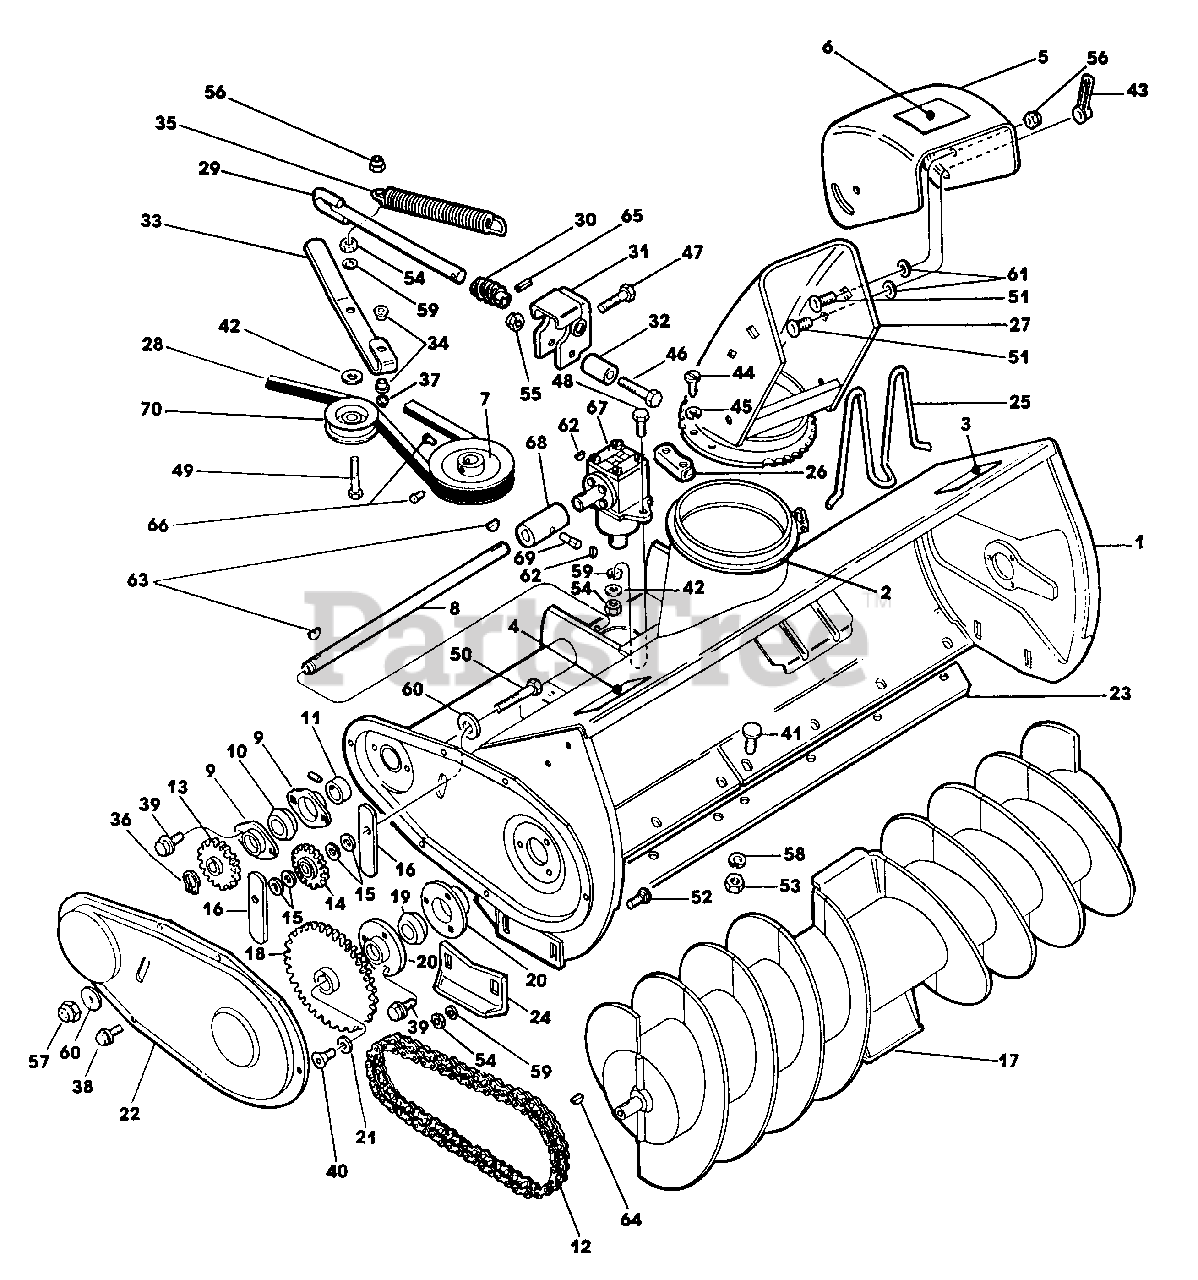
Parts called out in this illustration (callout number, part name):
1	Collector Housing Ass'y. w/Decals
2	Chute Collar
3	Decal-Warning
4	Decal-Danger
5	Chute Deflector & Decal Ass'y
6	Decal-Danger
7	Pulley, 4 1/2" Diameter
8	Output Shaft
9	Flangette Stamping
10	Bearing
11	Collar w/Setscrews
12	Chain
13	Sprocket
14	Idler Sprocket
15	Spacer
16	Strip
17	Auger
18	Sprocket
19	Bearing
20	Flangette Stamping
21	Washer
22	Drive Cover
23	Scraper Blade
24	Skid
25	Discharge Guard
26	Retainer
27	Discharge Chute
28	V-Belt (Secondary)
29	Worm Shaft
30	Worm Gear
31	Worm Support
32	Spacer-Worm Support
33	Idler Arm Assembly w/Bushings
34	Bushing
35	Spring-Idler
36	Snap Ring
37	Snap Ring
38	Lock Screw
39	Lock Screw
40	Flat Socket Hd. Screw
41	Wafer Hd. Bolt
42	Washer, Flat
43	Wing Nut
44	Screw, Self Tapping
45	Lock Washer, #6
46	Cap Screw, Hex Hd
47	Cap Screw, Hex Hd
48	Cap Screw, Hex Hd
49	Cap Screw, Hex Hd
50	Cap Screw, Hex Hd
51	Bolt, Carriage
52	Bolt, Carriage
53	Nut, Hex
54	Nut, Hex
55	Nut, Hex Cone Lock
56	Nut, Hex Cone Lock
57	Nut, Hex Cone Lock
58	Washer, Spring Lock
59	Washer, Spring Lock
60	Washer, Flat
61	Washer, Flat
62	Key, Woodruff
63	Key, Woodruff
64	Key, Woodruff
65	Roll Pin
66	Setscrew, Square Hd. Cup Pt
67	Gear Box, R.H
68	Coupling
69	Drive Pin, Grooved
70	Idler Pulley
